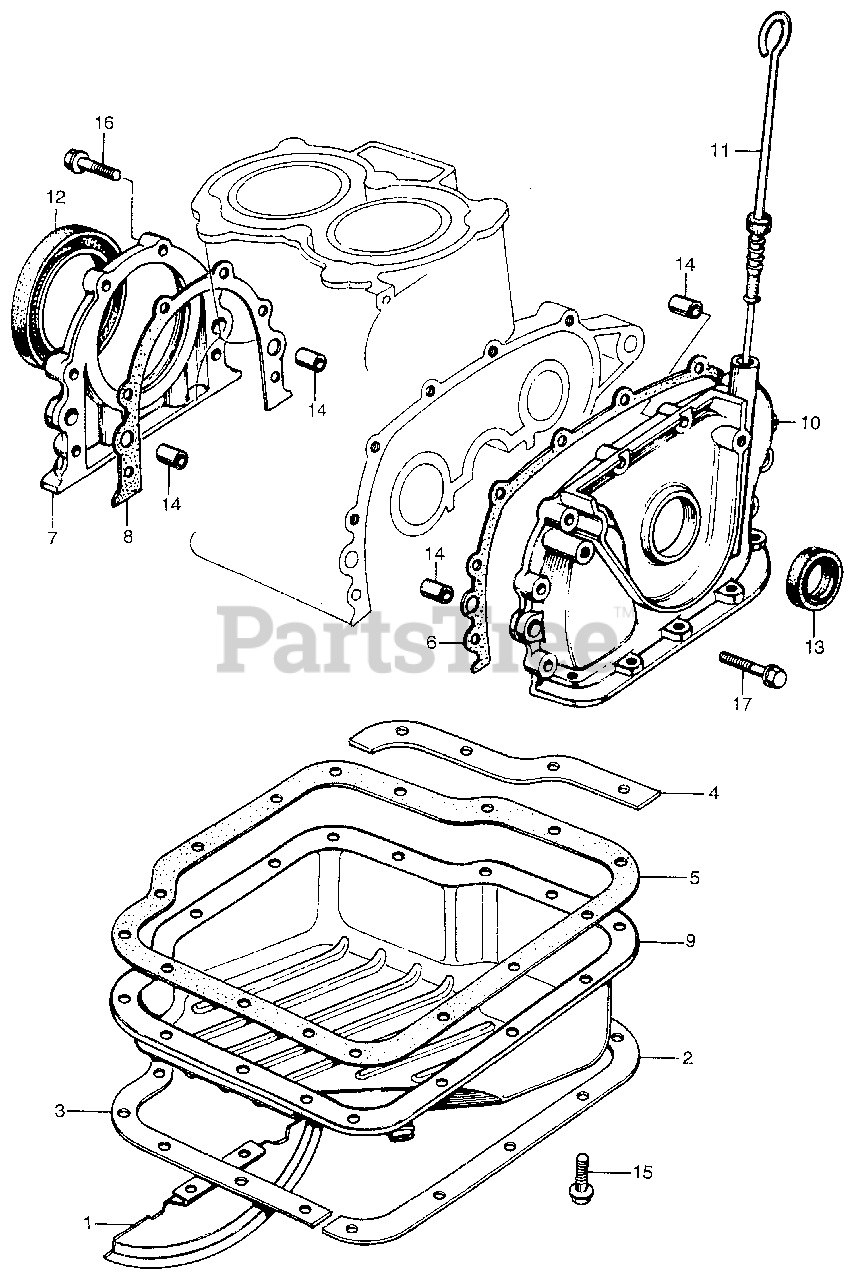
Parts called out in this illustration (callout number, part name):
1	PLATE, SEAL
2	STIFFENER A, OIL PAN
3	STIFFENER B, OIL PAN
4	STIFFENER C, OIL PAN
5	GASKET, OIL PAN
6	GASKET, L.
7	COVER, R. SIDE
8	GASKET, R. SIDE COVER
10	COVER, L. SIDE
11	DIPSTICK, OIL (NOT AVAILABLE)
12	OIL SEAL (58X80X10) (NOK)
13	OIL SEAL (35X50X8)
14	PIN A, DOWEL (14X20)
15	BOLT, FLANGE (6X18)
16	BOLT, FLANGE (6X25)
17	BOLT, FLANGE (6X32)
